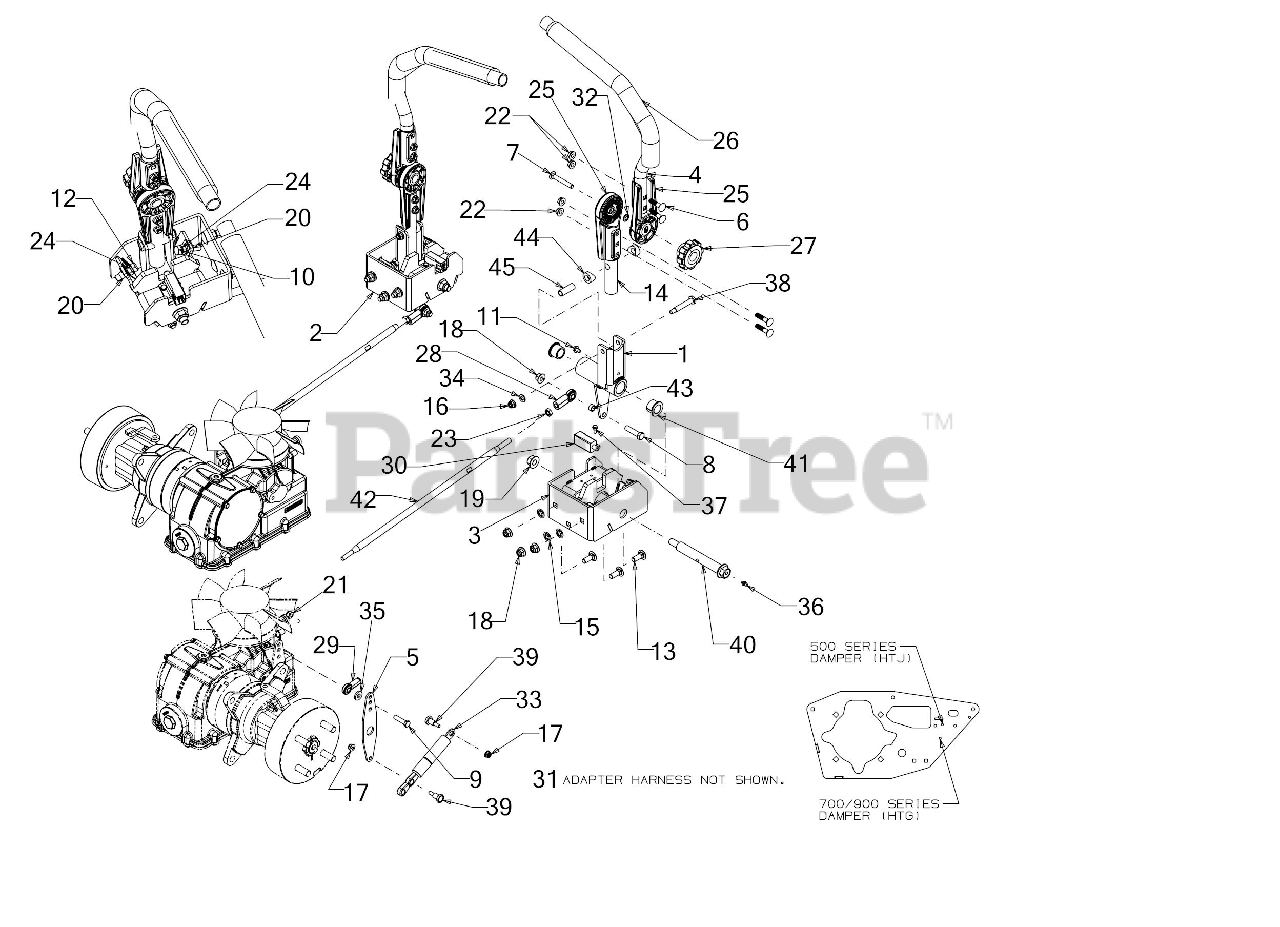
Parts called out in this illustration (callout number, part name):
1	LAPBAR PIVOT CONTROL ASSEMBLY
5	DAMPENING CYLINDER MOUNTING BRACKET
6	CARRIAGE BOLT 5/16-18 x 1.50
7	SCRE W5/16-18 x 2.25 GR5
8	SCREW 3/8-16 x 1.50
9	SCREW 5/16-18 x 1.25 GR5
10	SCREW 3/8-16 x 1.50 GR8
11	SCREW 1/4-20 x .375
12	SCREW 3/8-16 x 1.25 GR5
13	CARRIAGE BOLT 3/8-16 x 1.00 GR5
16	FLANGE LOCK NUT 5/16-18
17	FLANGE LOCK NUT
20	U NUT 3/8-16
21	HEX NUT
22	FLANGE NUT
23	HEX JAM NUT 3/8X24
25	HANDLE ADJUST
27	KNOB-5/16-18
28	BALL JOINT (RH)
29	END ROD- 5/16 (LH)
30	INTERLOCK SWITCH (NO/NC)
31	ADAPTER HARNESS - LAPBAR
33	DAMPENING CYLINDER
34	FLAT WASHER
35	FLAT WASHER
36	GREASE ZERT 1/4-28
37	SHOULDER SCREW
38	SHOULDER SCREW
39	SHOULDER BOLT .395 DIA x .56 LG
40	SHOULDER BOLT 1.0 X 4.75 1/2-13
41	FLANGE BEARING
42	PUMP CONTROL ROD
44	NYLON SPACER
